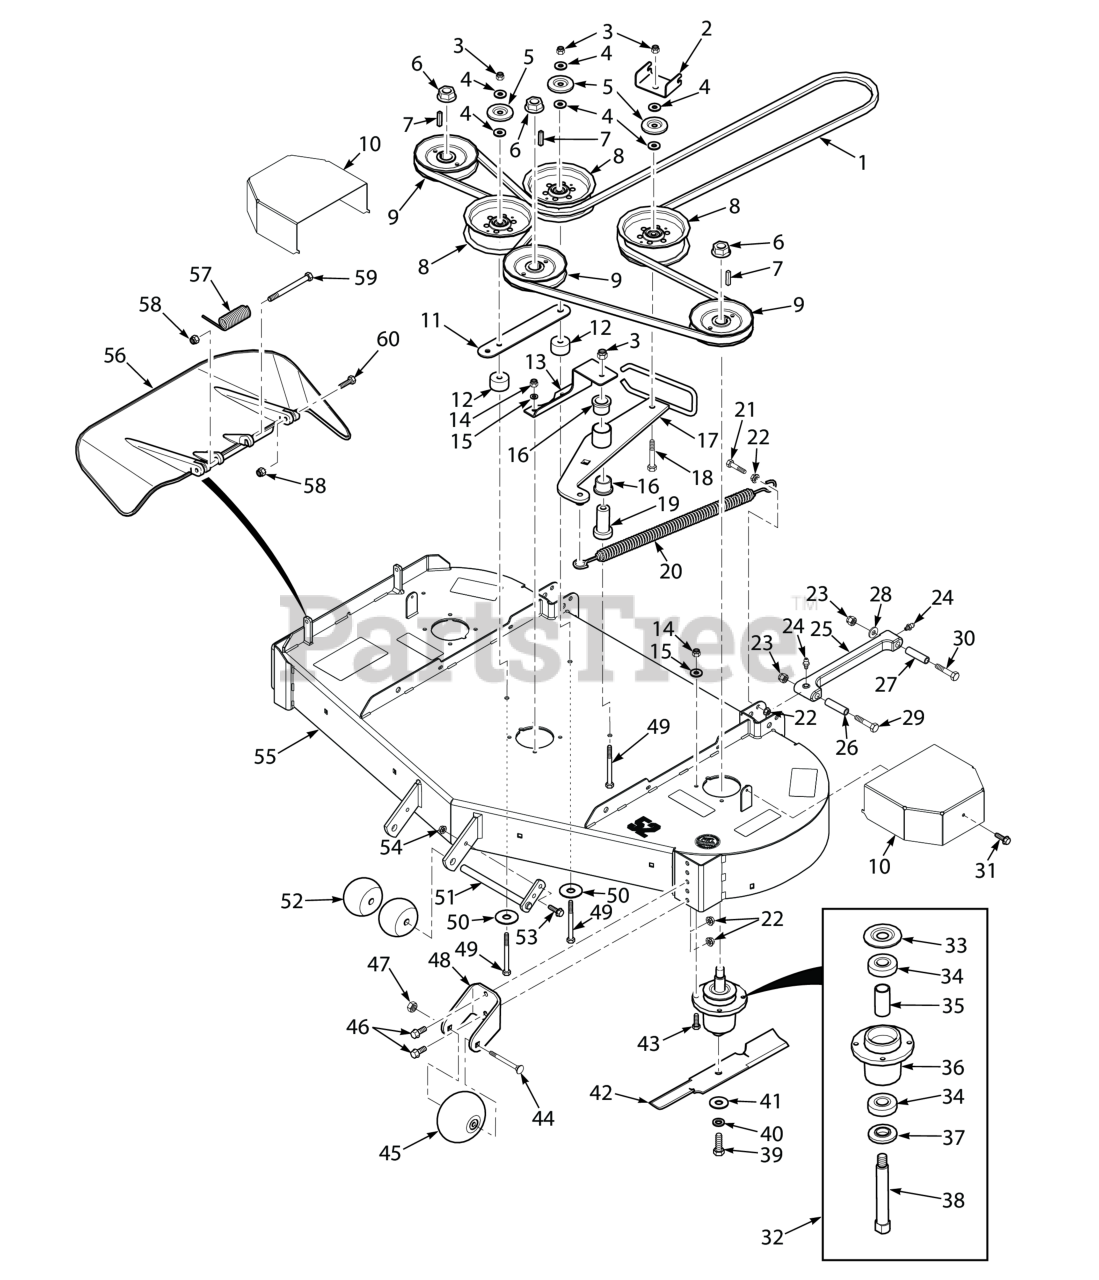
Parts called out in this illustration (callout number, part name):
1	Belt, Cutter Deck - 52
2	Bracket, Belt Guide
3	HEX NUT, ELASTIC STOP LOCK, 3/8-16
4	Flatwasher, 3/8 (.391 x .938 x .105 HD) Grade 8
5	Quick Pin, 5/16" Dia.
6	Nut, 3/4-16 Spriral Lock
7	Key, 1/4 x 1/4 x 1.25" Pulley Mtg.
8	Pulley, 5" Idler
9	Pulley, 5.73" OD - 25mm Bore
10	Belt Cover, SZL
11	Brace, Pulley
12	Spacer, Idler Pulley
13	Support, Idler Pivot - 52
14	Lock Nut, 5/16-18 Elastic Stop Grade 8
15	Lockwasher, 5/16 (.317 x .586 x .078) Helical Spring
16	Bearing, Plastic
17	Idler Arm (incl. item #15)
18	Capscrew, Hex Head 3/8-16 x 2-1/2"
19	Pivot, Idler
20	Spring, Cutter Deck Idler
21	Bolt, Hex Head 3/8-16 x 1-1/2" Grade 8 Black
22	NUT, 3/8-16 SERRATED FLANGE HEX HEAD
23	HEX LOCKNUT, ELASTIC STOP, 1/2-13
24	GREASE FITTING, STR. 1/4-28 SELF TAP.
25	Pusharm Assembly, LH
26	Spacer, Pusharm - Deck
27	Spacer, Pusharm - Axle
28	Flatwasher, 1/2 - .531 x 1.062 x .095
29	Bolt, Hex Head 1/2-13 x 3-1/2"
30	Bolt, Hex Hd. 1/2-13 x 2-1/2" (lower)
31	Screw, 1/4-20 x .375"
32	Spindle Assembly
33	Debris Shield
34	Bearing
35	Spacer, Bearing
36	Spindle Housing Assembly
37	Protector, Bearing
38	Shaft, Spindle
39	Bolt, Hex Head 5/8-11 x 1-1/2"
40	Lockwasher, 5/8" Spring
41	Flatwasher, 5/8-.688 x 1-3/4 x .134 HD
42	Cutter Blade, 18" (52V)
43	Bolt, Hex Head 5/16-18 x 1-1/2" Grade 8
44	Bolt, Hex Head 3/8-16 x 3-1/2"
45	Bolt, Carriage 3/8-16 x 4"
46	Capscrew, 3/8-16 x 1.0" Serrated Flange Hex Hd
47	Bolt, Hex Head 3/8-16 x 1" Ser. Flg.
48	Bracket, Anti-Scalp, (Black)
49	Bolt, Hex Head, 3/8-16 x 3-1/2"
50	Flatwasher, 3/8-.406 x 2.25" x .1875
51	Shaft Weldment, Guide Roller
52	Wheel, Anti-Scalp
53	Bolt, Heax Head 5/16-18 x 1" (48V / 52V)
54	Nut, Flange Head Elastic Stop 5/16-18
55	Cutter Deck w/Decals, SWZT52H
56	Discharge Chute Assy. SFZ52
57	Spring, Discharge Chute
58	HEX NUT, ELASTIC STOP LOCK, 5/16-18
59	Bolt, 5/16-18 x 4-3/4" Hex Head
60	Bolt, Hex Head 5/16-18 x 1-1/2" - Front
